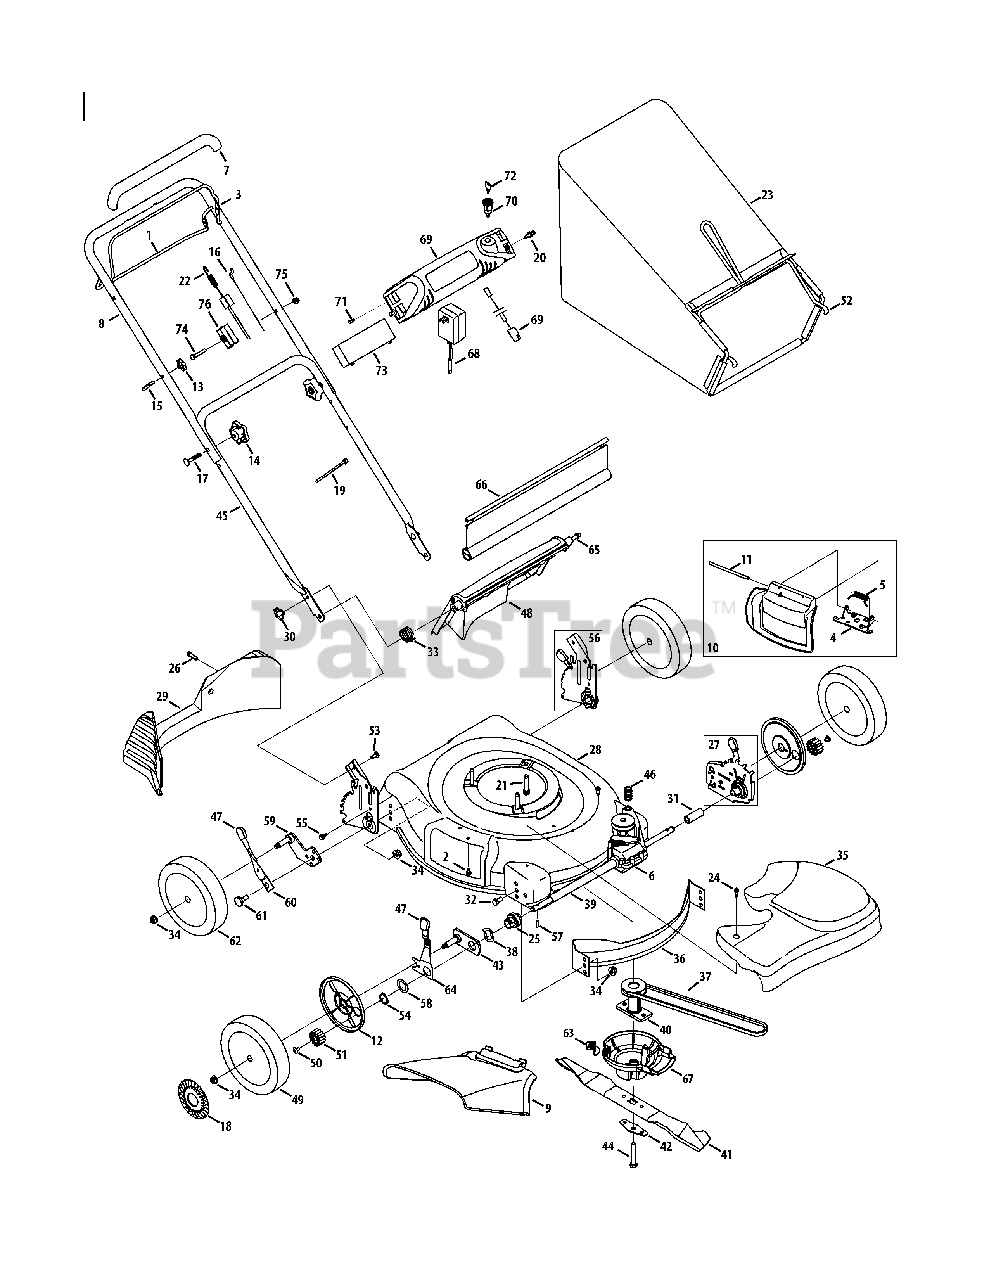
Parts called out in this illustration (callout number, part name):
1	Drive Control
3	Blade Control
4	Deflector Chute Adapter
5	Torsion Spring
6	Transmission Assembly
7	Blade Control Cover
9	Chute Deflector
10	Mulch Plug Complete
12	Wheel Dust Cap
13	Handle Knob
16	Control Cable
17	Carriage Bolt 5/16-18 x 2.0
19	Cable Tie
21	Self-Tapping Sems Screw
22	Drive Cable
23	Grass Bag
24	Shoulder Screw # 12 -24
25	Front Bearing Assembly
26	Screw, 1/4-15 x 1.000
27	Height Adjustment Ass’y - RH
27	Height Adjustment Ass’y - LH
29	Rear Baffle
30	Wing Nut
31	Slev. Spacer 1.4" Lg.
32	Hex Screw, 3/8-16 x.75
33	Torsion Spring - RH
34	Flange Lock Nut, 3/8-16
35	Transmission Cover
36	Front Baffle
38	Wave Washer
39	Sleeve Spacer 8.985" Lg.
40	Blade Adapter
41	21" Mulching Blade
42	Blade Bell Support
43	Pivot Plate Assembly
44	Hex Screw 3/8-24 x 2.50
46	Belt Tension Spring
47	Adjustment Knob
48	Rear Discharge Door
49	Front Wheel
50	Screw, 1/4-20 x .390
51	Gear 14T RH FWD
51	Gear 14T LH FWD
52	Grass Bag Frame
53	Carriage Bolt 1/4-20
54	Snap Ring
55	TT Scr. w/Washer 1/4-20 x.625
56	Handle Bracket Assembly - RH
56	Handle Bracket Assembly - LH
57	Dowel Pin
59	Pivot Arm Assembly - RH
59	Pivot Arm Assembly - LH
60	Rear Spring Lever
61	Shoulder Scr.500 Dia. x.434
63	Engine Baffle Bracket
64	Front Lever - RH
64	Front Lever - LH
66	Rear Trailing Shield
67	Engine Baffle
68	Battery Charger
69	Electric Start Harness Ass’y.
70	Key Switch
71	Screw, #10-16 x .750
73	Battery
74	Screw, 1/4-20 x 1.50
75	Nut, Flglk, 1/4-20
76	Control Cable Mount
